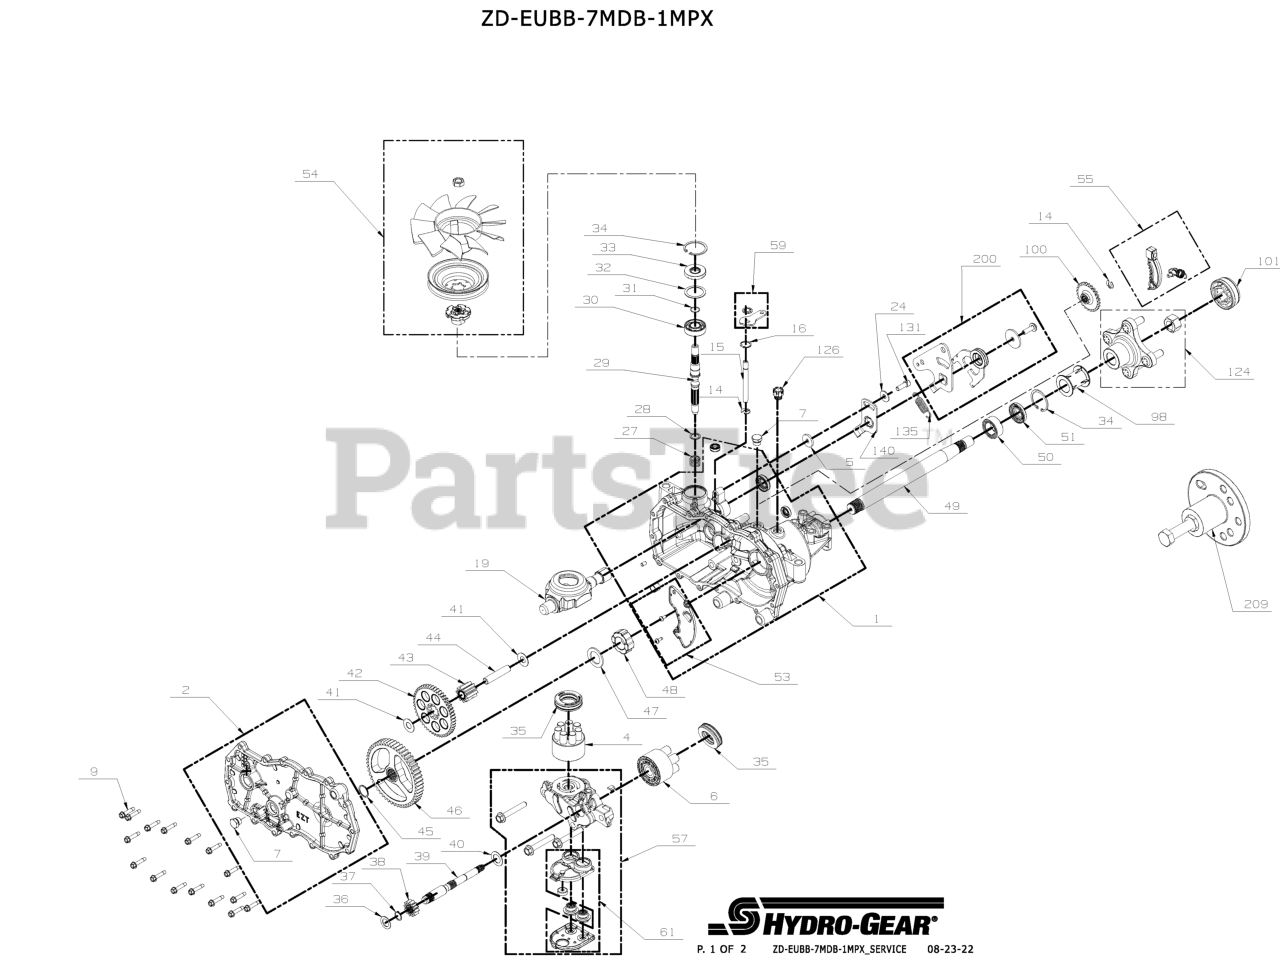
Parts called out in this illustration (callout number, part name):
1	ASSEMBLY, MAIN HOUSING
2	KIT, SIDE HOUSING, RH W/DRAIN
4	ASSY, BLOCK 7 PISTON
6	KIT, 10 CC BLOCK
7	PLUG EXT HEX VENT 9/16 18
9	SCREW,HEX WASHER 1/4-20X1.125
14	RING. RETAINING
15	ROD, BYPASS
16	RING, RET .750
19	TRUNNION, SWASHPLATE
27	SPRING. BLOCK
28	WASHER. THRUST .59 X .79 X .04
29	SHAFT, INPUT
30	BRG, BALL 17X40X12
31	RING, RET WIRE .561 ID
32	WASHER 1.23X1.56X.04
33	SEAL, LIP 17X40X7
34	RING, RET 1.56 INT
35	BEARING. THRUST 30 X 52 X 13
37	RING, RET 62 EXT
39	SHAFT, MOTOR
40	WASHER .71 X 1.16 X .04
41	WASHER .5X1.0X.032
43	GEAR, 10T JACKSHAFT
44	PIN, JACKSHAFT
47	WASHER, 1.018 X 1.571 X .105 FLAT
48	BUSHING, SLEEVE (INBOARD)
49	SHAFT, AXLE
52	KIT, SEALS AND RETAINING
53	KIT, EXPANSION PLATE RH
54	KIT, FAN/PULLEY
55	KIT, BRAKE ARM
57	KIT, CENTER SECTION RH
58	SEALANT TUBE 10.1OZ.
59	KIT, BYPASS ARM
61	KIT, FILTER
100	DISC, COG BRAKE
101	CAP, AXLE
124	KIT, HUB 4 BOLT
126	ASSEMBLY, FITTING 9/16-18 BREATHER
131	KIT, RTN SCREWS
135	SPRING, EXTENSION
140	ARM, NEUTRAL RIGHT
200	KIT RTN BIDIRECTIONAL
209	HUB PULLER 5 BLT
